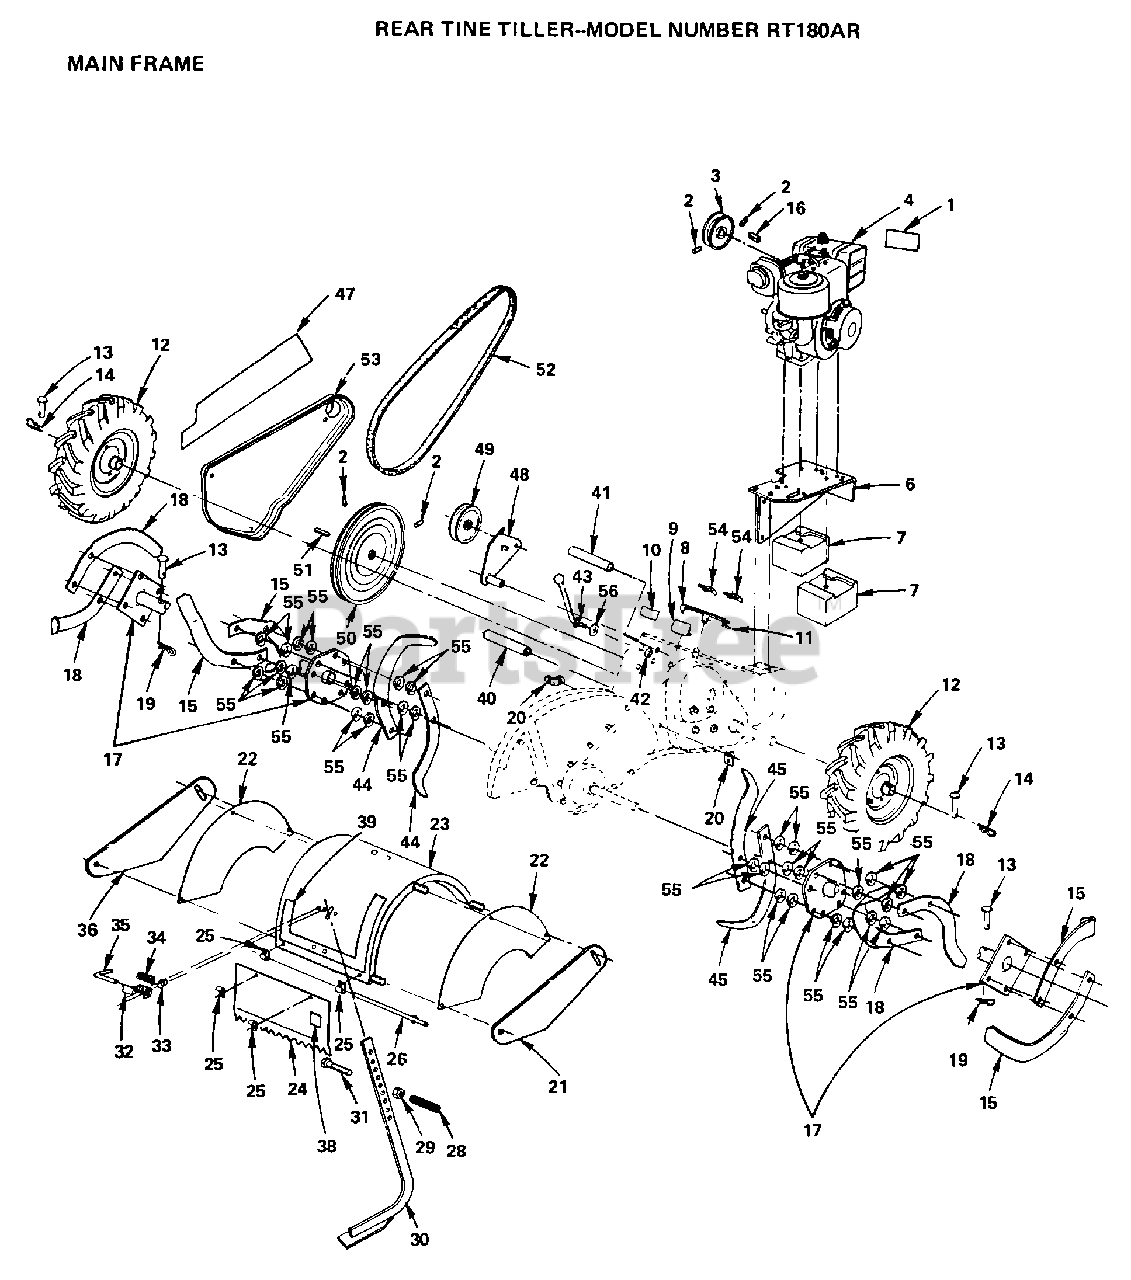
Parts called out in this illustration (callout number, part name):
3	SHEAVE CRT
4	ENGINE - 8 HP
8	LEVER ASSY T
10	DECAL, SHIFT INDICATOR
12	WHEEL TI
13	RIVET.PAN HD.1.75
14	SPRING.RETAINER
16	KEY TI
17	TINE ASSY CRT
19	RETAINER.SPRING
20	TINE SHLD BRKT TI
25	HINGE CRT
26	PIN HINGE CRT
28	GRIP TI
29	NUT.HEX.3/8-16UNC
32	LATCH BRACKET TI
33	KLIP RING TI
34	SPRING TI
35	STAKE PIN TI
39	DECAL - TINE SHIELD
40	SPACER TI
41	SPACER TI
42	NUT FLANGE CRT
43	HANDLE LOCK CRT
44	TINE.LH.CRT
45	TINE RH CRT
47	DECAL - BELT GUARD
50	"SHEAVE 10"" CRT"
51	KEY T
54	CONDIUT CLIP T
55	LOCKWASHER
56	WASHER
